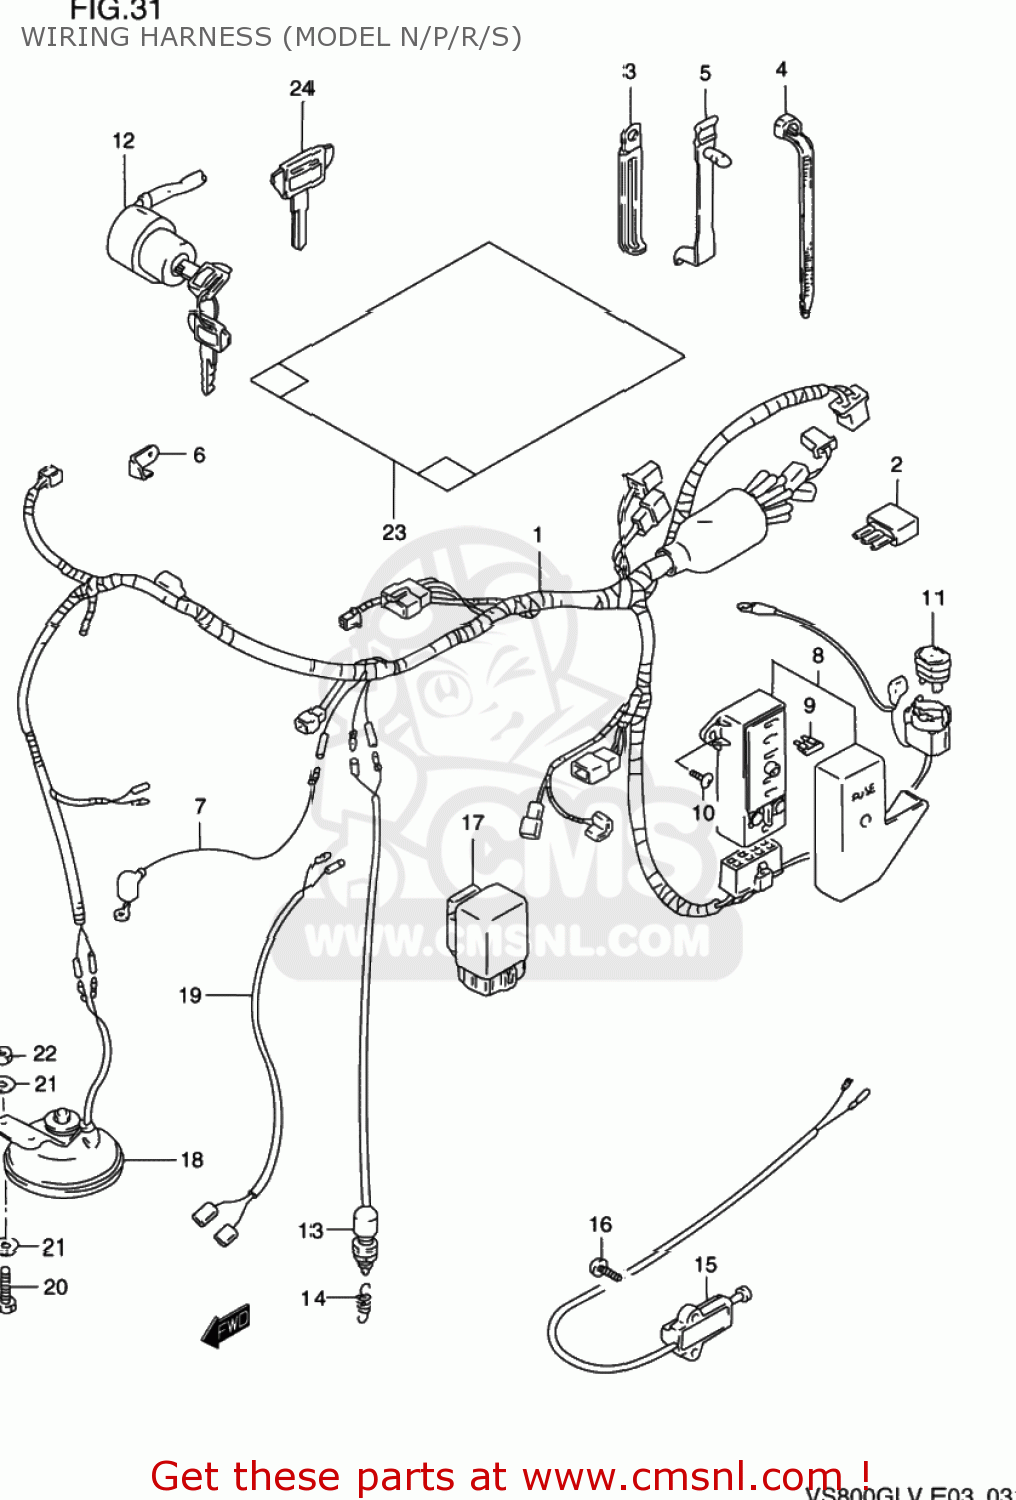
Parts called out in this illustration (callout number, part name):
1	HARNESS,WIRING
2	DIODE(STANLEY DE8804)
3	CLAMP
4	CLAMP L:165
5	CLAMP,L:88
6	PLATE,COUPLER HOLDER
7	WIRE,WATER TEMP GAUGE LEAD
8	BOX ASSY,FUSE
9	FUSE(10A)
10	SCREW
11	BREAKER ASSY,CIRCUT
12	SWITCH ASSEMBLY,IGNITION
13	SWITCH ASSY,STOP LAMP
14	SPRING
15	SWITCH ASSEMBLY,SIDE STAND
16	SCREW
17	RELAY ASSEMBLY
18	HORN ASSY
19	WIRE,HORN LEAD
20	BOLT
21	WASHER
22	NUT
23	COVER,WIRING HARNESS
24	KEY,BLANK(TYPE:C)
